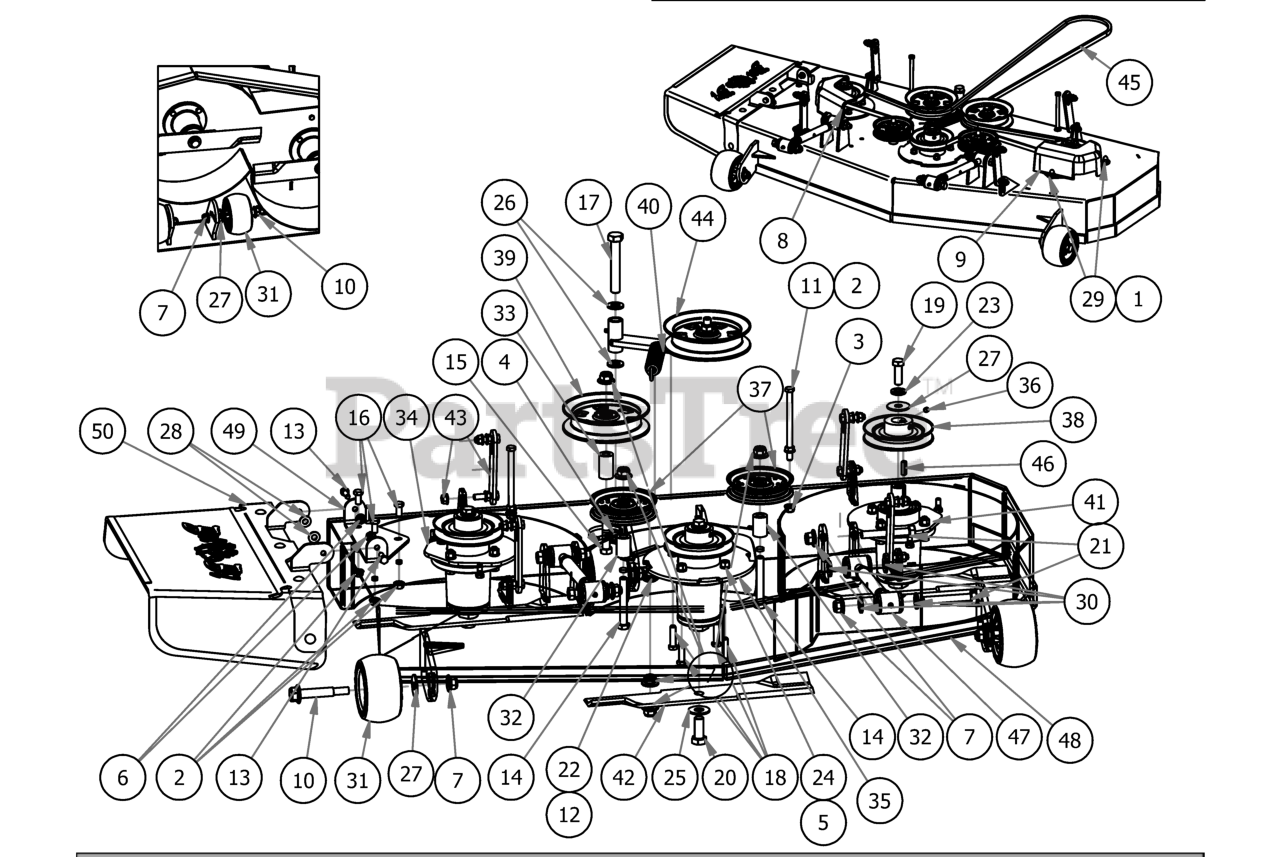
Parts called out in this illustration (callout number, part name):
1	Acorn nut-pulley Cover
2	3/8" Flange Nut
3	3/8" Nylock Flange Nut
4	5/8-11 Nylon Insert Jam Half Nut
5	3/8" Hex Nut
6	5/16" Nylon Flange Nut
7	1/2-13 Nylon Flange Nut
8	pulley cover chute side
9	pulley cover non-chute side
10	Deck Wheel Bolt
11	3/8-16 X 5-1/4 HEX CAP SCREW (GR.5) ZINC
12	1/2 x 2" Carriage Bolt
13	5/16-18 x 1 GR 5 Hex Bolt Zinc
14	1/2 x 3 1/2 Flange Bolt Grade 8
15	1/2" x 4" Bolt (Grade 8)
16	3/8" x 3/4" Hex Bolt
17	5/8" x 4" Hex Bolt
18	3/8 x 1.5" Bolt
19	1/2"-20 x 1 1/2 - Grade 5 Fine Thread Bolt
20	5/8 x 1 1/2 Grade 8 Hex Bolt (Fine)
21	1/2-13 x 3 1/2 GR 5 Hex Bolt
22	.517 Square Hole Round Washer
23	1/2" Lock Washer Zinc
24	3/8" Lock Washer
25	5/8'' Flat Washer
26	.630 ID Plastic Washer
27	1/2" Belleville Washer
28	.360 ID Plastic Washer
29	.360 ID Plastic Washer-Black
30	.505 Nylon Spacer
31	Deck Wheel
32	.502 ID X .750 OD X 1.500 Long Spacer
33	1 3/4" Pulley Spacer
34	42&48 Deck Spindle Support Plate
35	Deck Spindle Support Plate
36	5/16 Set Screw
37	4 3/4 Idler Pulley - ABFI-76
38	5" Spindle Deck Pulley
39	5-3/4 Idler Pulley
40	Deck Idler Spring
41	Spindle Assembly
42	16 1/4" Bad Boy Blade
43	Deck Hanger Assembly
44	2017 54"/48" Deck Idler Assembly
45	B147 Deck Belt
46	1/4" x 1" Key
47	2018 Maverick Turnbuckle (Top Link)
48	2017 48" ZT Deck
49	Discharge Chute Hanger (deck mounted)
50	ZT Chute Assembly
